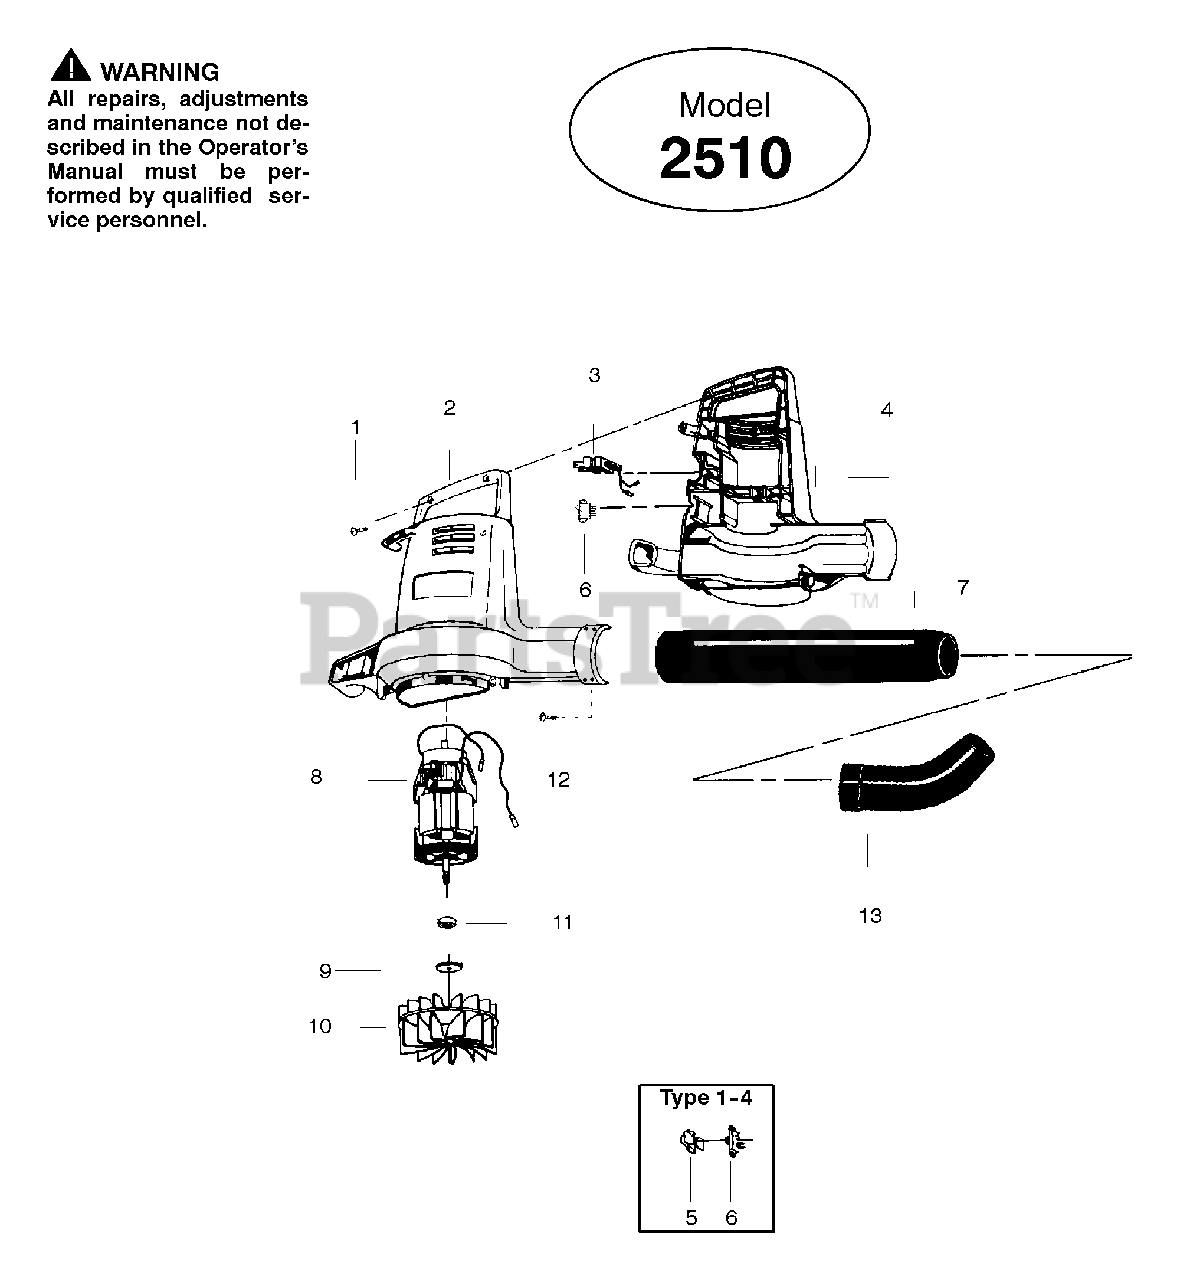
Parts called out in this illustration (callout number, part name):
2	Housing Set Type 1
2	Housing Set Type 2
2	Housing Set Type 3 & 4
2	Housing Set Type 5
3	Wire Harness Type 1 & 2
3	Wire Harness Type 3 & 4
3	Wire Harness Type 5
4	Pad (Type 1 & 2)
5	Switch Cover (Type 1-4 ONLY)
6	Switch Type 1-4
6	Switch Type 5
7	Blower Tube Type 1
7	Blower Tube Type 2-5
8	Motor Ass'y. Type 1 & 2
8	Motor Ass'y. Type 3
8	Motor Ass'y. Type 4 & 5
10	Impeller
11	Spacer (Type 4 & 5)
12	Screw (Type 2-5)
13	Concentrator Nozzle Type 1
13	Concentrator Nozzle Type 2-5
